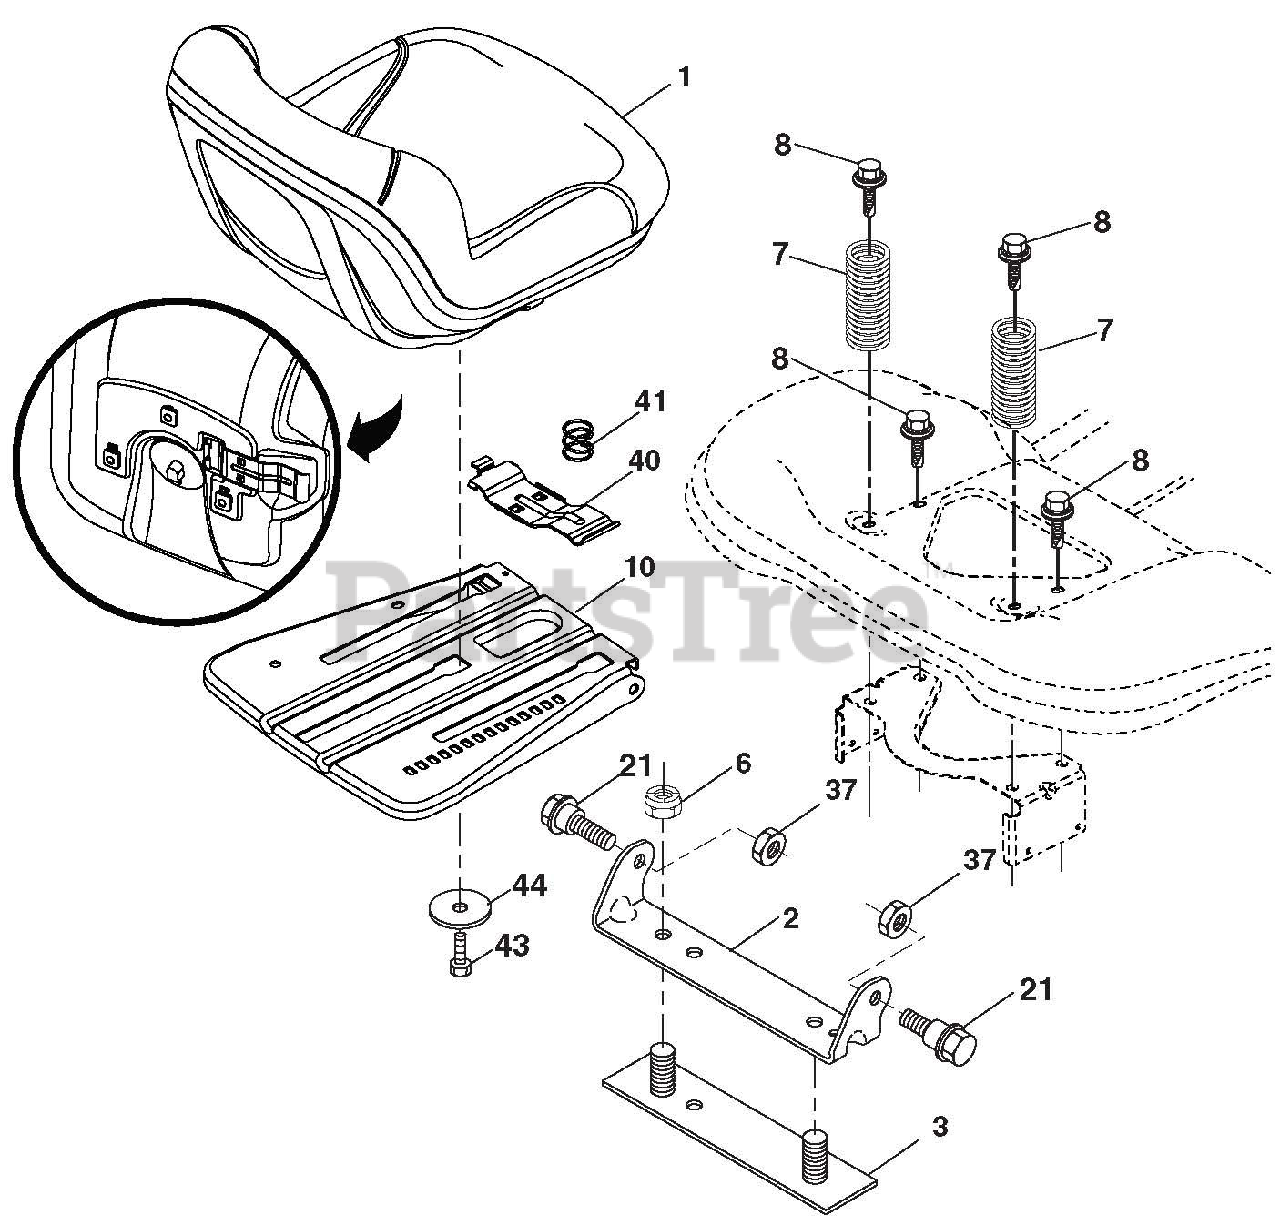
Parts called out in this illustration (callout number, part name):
1	SEAT.TA150.KB/SLD.BLK.ARIENS
2	BRACKET.PIVOT.FENDER.2002
3	STRAP ASM.FENDER.94
6	Locknut, Washer Insert 3/8-16
7	SPRING.SEAT.CPRSN.2.250.BLK.ZI
8	BOLT.5/16-18UNCX3/4 W/SEMS.BLK
10	PAN ASM.SEAT.3PT.
21	BOLT.SHLD.5/16-18 UNC-2A.BLK D
37	Locknut, Washer Insert 5/16-18
40	HANDLE.SLIDE.SEAT.TEX.MILSCO
41	SPRING.LATCH.SEAT.TEX
43	BOLT.FIN.HEX.3/8-16UNC X 3/4
44	WASHER.13/32 X 2 3/8 X 12GA.
